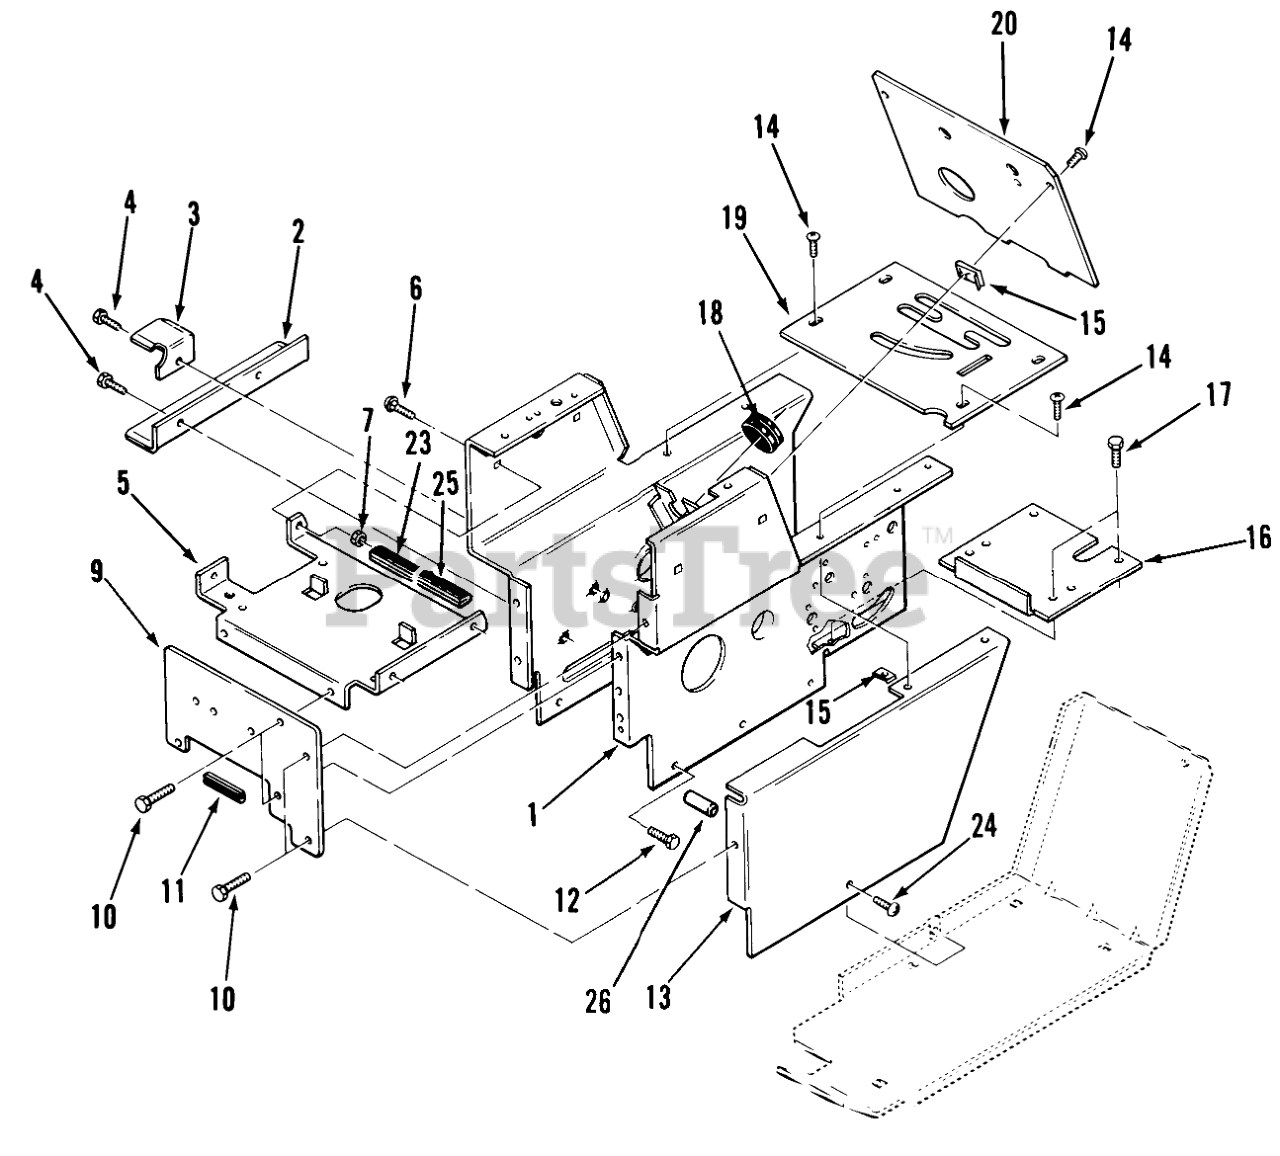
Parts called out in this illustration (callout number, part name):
1	Hoodstand
2	ANGL-BLT GURDB
3	BRCKET-BLT SUTB
3	Belt Bracket
4	SCREW
5	SUPPORT-BATTERY B
6	CARRIAGE BOLT -4
7	Nut
9	Front Plate
9	Front Plate C-161 Twin Only
9	FRONT PLATE ASSY B
10	SCREW
11	EDGE TRIM 2" 102896
12	SCREW
12	Bolt
13	Side Cover LH
13	COVER LH R
14	SCREW-PPH
16	Cover-Dust
17	SCREW
18	GROMMET
19	PLATE SHIFT B
19	PLATE SHIFT PATTE B
19	Plate-Shift Cover
20	PLATE HOODSTAND B
20	PLATE-HOODSTAND R B
20	Plate-Hood Stand
20	Hoodstand Plate
23	EDGE TRIM 5" OF 102896
24	Screw
24	Pan Head Screw 1/4-20 x 1 3/4
25	EDGE TRIM 2" 102896
26	Spacer
